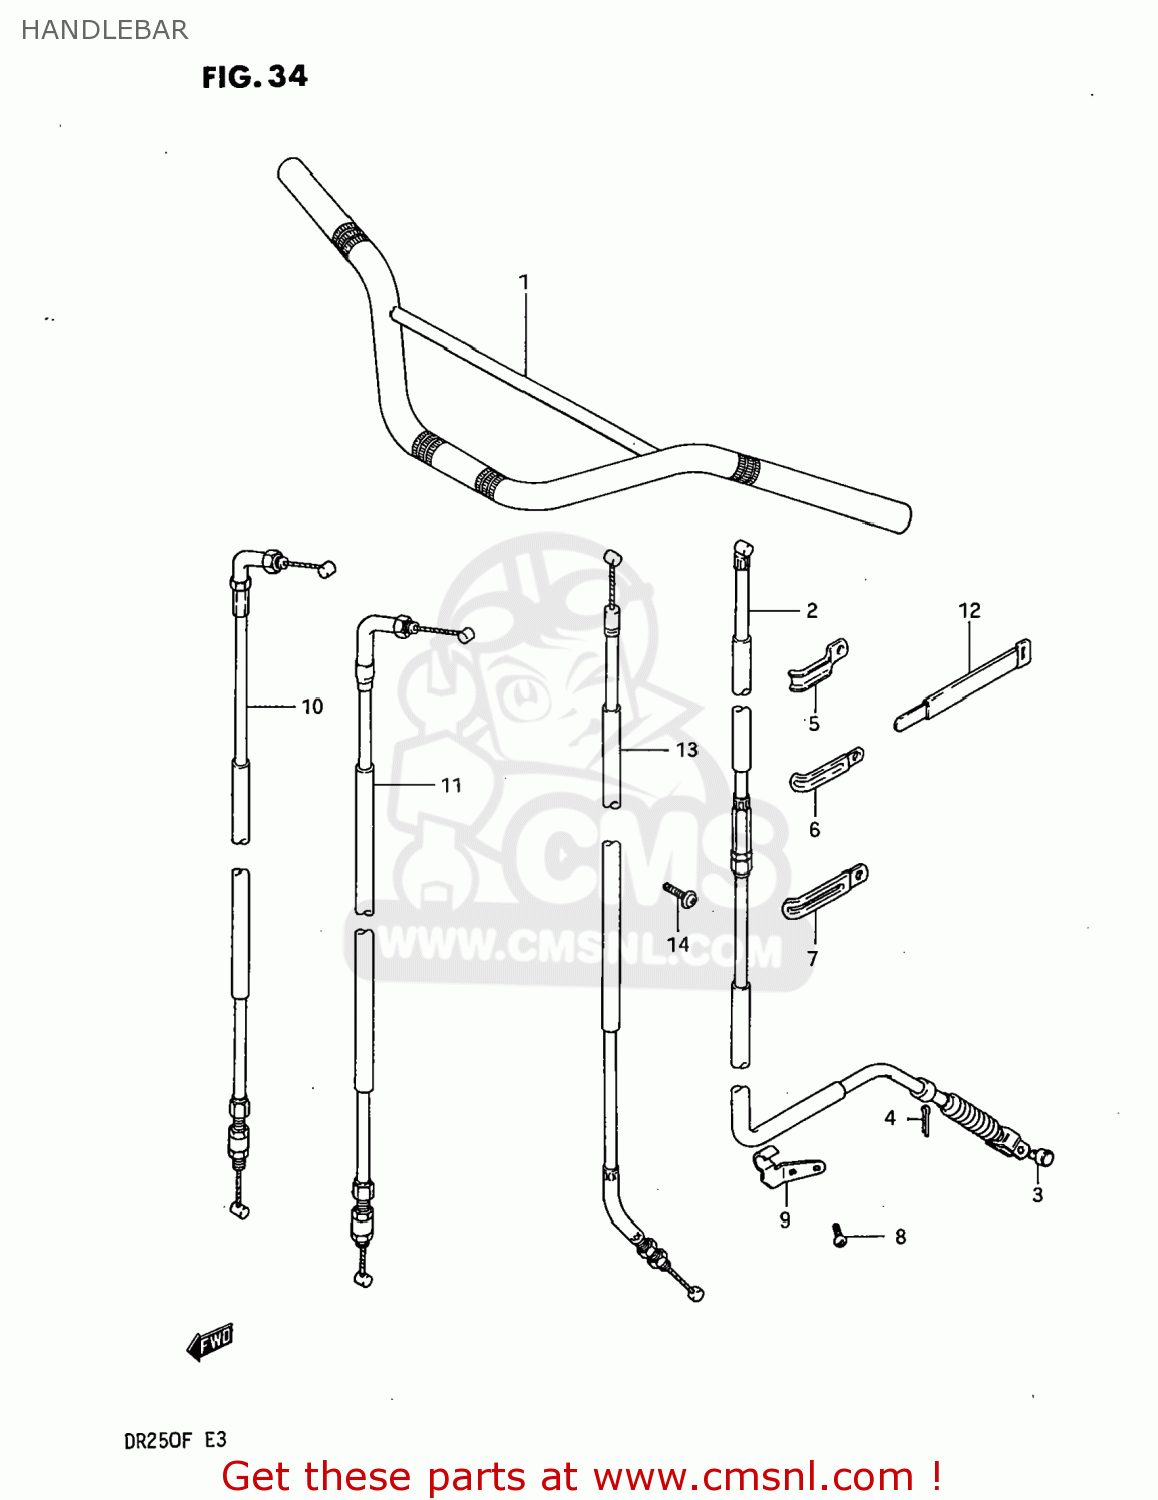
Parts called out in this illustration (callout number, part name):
1	HANDLEBAR
2	CABLE ASSEMBLY,CLUTCH
3	PIN(L:13)
4	PIN
5	CLAMP
6	CLAMP
7	CLAMP
8	SCREW
9	STOPPER,CLUTCH CABLE
10	CABLE ASSY,THROTTLE NO.1
11	CABLE ASSY,THROTTLE NO.2
12	CLAMP(L:250)
13	CABLE ASSEMBLY,DECOMPRESSION
14	SCREW
